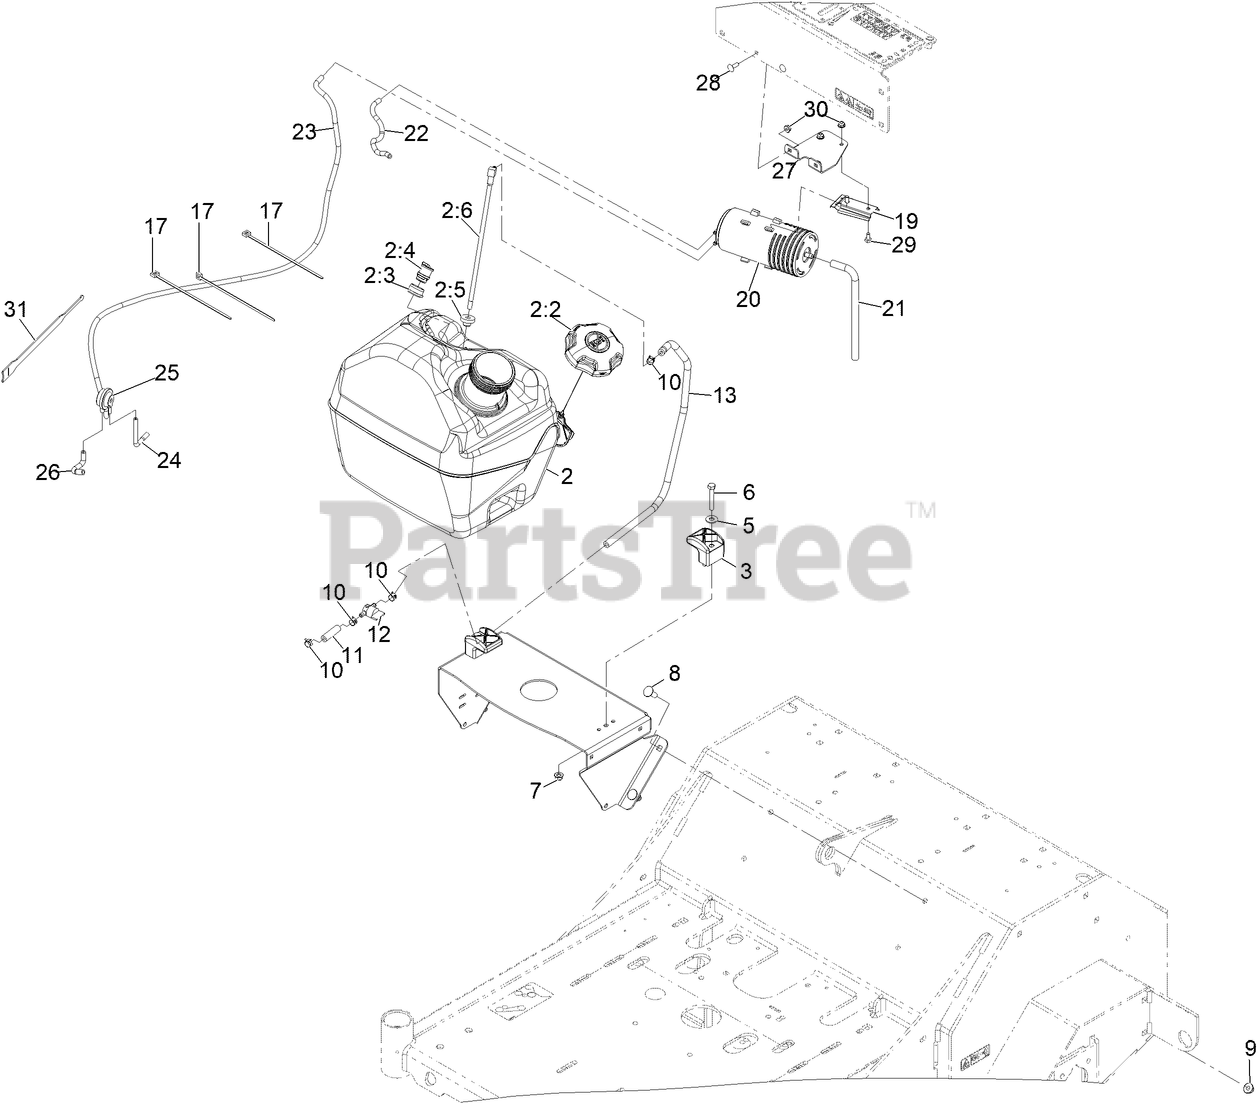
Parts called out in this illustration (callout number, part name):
2	Fuel Tank ASM, 5 Gal
2:2	CAP-FUEL, RATCHETING
2:3	GROMMET
2:4	VALVE-VENT, FUEL
2:5	BUSHING
2:6	FITTING, FUEL W/LINE AND SCREEN
5	WASHER-FLAT
6	SCREW-HH
7	NUT-HF, NI
8	SCREW-CARR
9	NUT-HF, NI
10	CLAMP-HOSE
11	HOSE-FUEL
12	VALVE-FUEL
13	HOSE-LINE, GAS
17	TIE-CABLE
19	BRACKET-CANISTER, CARBON
20	CANISTER-CARBON, 800CC
21	HOSE-VENT, CANISTER
22	HOSE-EMISSIONS
23	HOSE-VENT, FORMED
24	HOSE-VENT, FORMED
25	VALVE-CONTROL, VACUUM
26	HOSE-VENT, FORMED
27	BRACKET-MOUNTING, CANISTE
28	BOLT-CARR
29	SCREW-HH
31	STRAP-VELCRO, CABLE TIE
